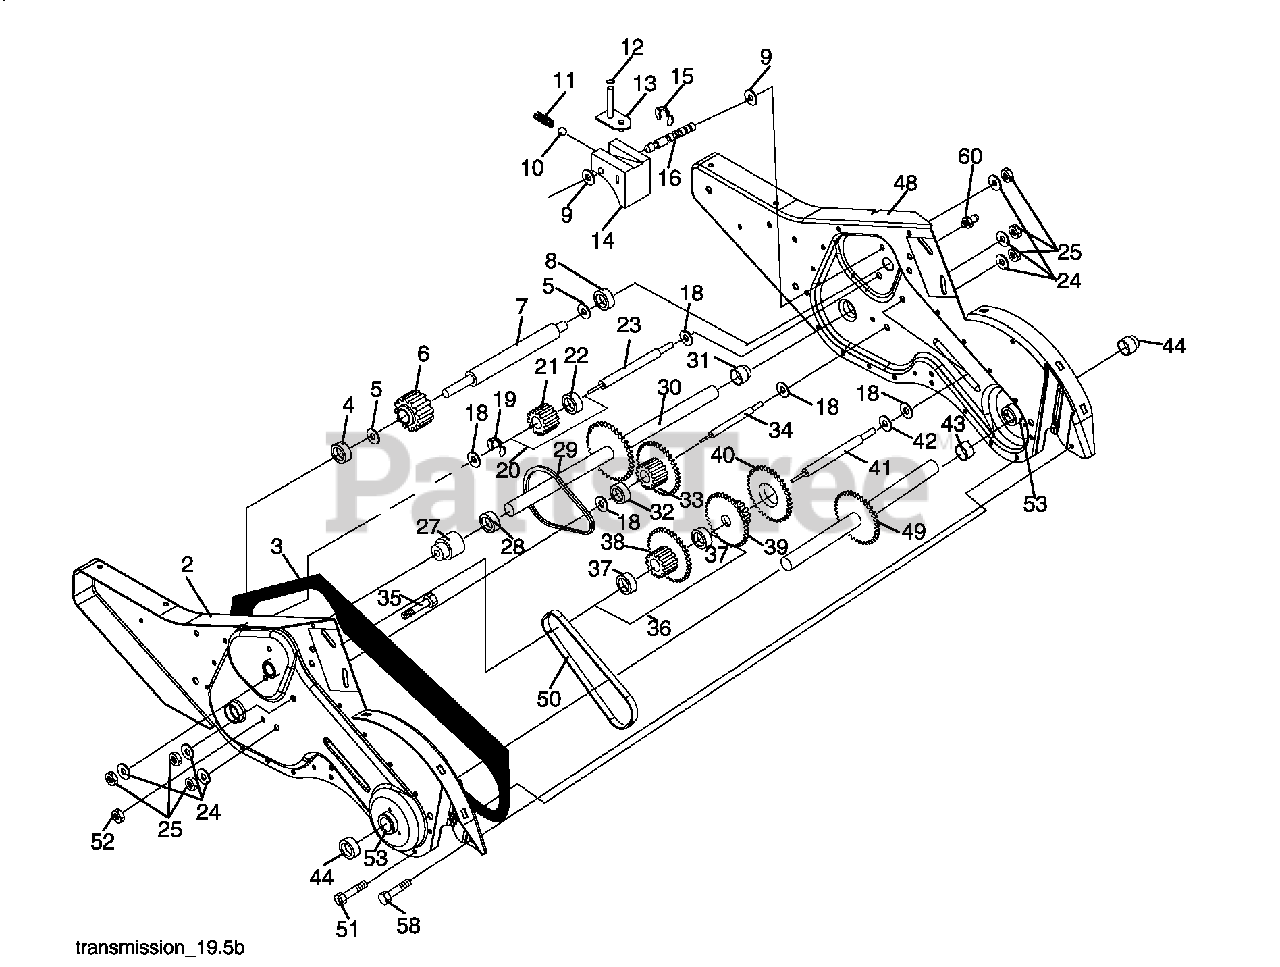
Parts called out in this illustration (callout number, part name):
1	Transmission Assembly
2	Gearcase, L.H. w/Bearing
3	Gasket, Gearcase
4	Bearing, Needle
5	Washer, Thrust 5/8 x 1.10 x 1/32
6	Pinion, Input
7	Shaft, In put
8	Bearing, Needle
9	Washer, Seal
10	Ball, Steel
11	Spring, Shift, Fork
13	Arm, Shift
14	Fork, Shift
15	Ring, Klip
16	Shaft, Shift
19	Ring, Klip
20	Gear, Assembly, Reverse Idler
21	Gear, Reverse Idler
22	Bearing, Needle
23	Shaft, Reverse Idler
24	Washer, Lock 7/16
25	Nut, Hex 7/16-20
27	Bearing, Shaft, Ground Drive L.H.
28	Spacer 0.765 x 1.125 x 1.23
29	Chain #35-50 Pitch
30	Ground Shaft Assembly
31	Bearing, Shaft, Ground Drive R.H.
32	Spacer 0.70 x 1.00 x 1.150
33	Sprocket and Gear Assembly
34	Shaft, Reduction (2nd)
35	Screw, Whiz, Lock 5/16-18 x 3-1/2
36	Sprocket Assembly w/Bearing
37	Bearing, Needle
38	Sprocket, Tine
39	Gear, Cluster, Red 1st & 2nd
40	Gear, Reverse
41	Shaft, Reduction (1st)
42	Washer, Thrust
43	Spacer 1.01 x 1.75 x 0.760
44	Seal Asm, Oil
48	Gearcase, R.H. w/Bearing
49	Shaft, Tine
50	Chain, Roller #50-50 Pitch
51	Screw 1/4-20 x 1/2
52	Nut, Hex 5/16-18
53	Kit, Bearing
58	Bolt Shoulder 1/4-20 unc x .875
60	Fitting Grease
